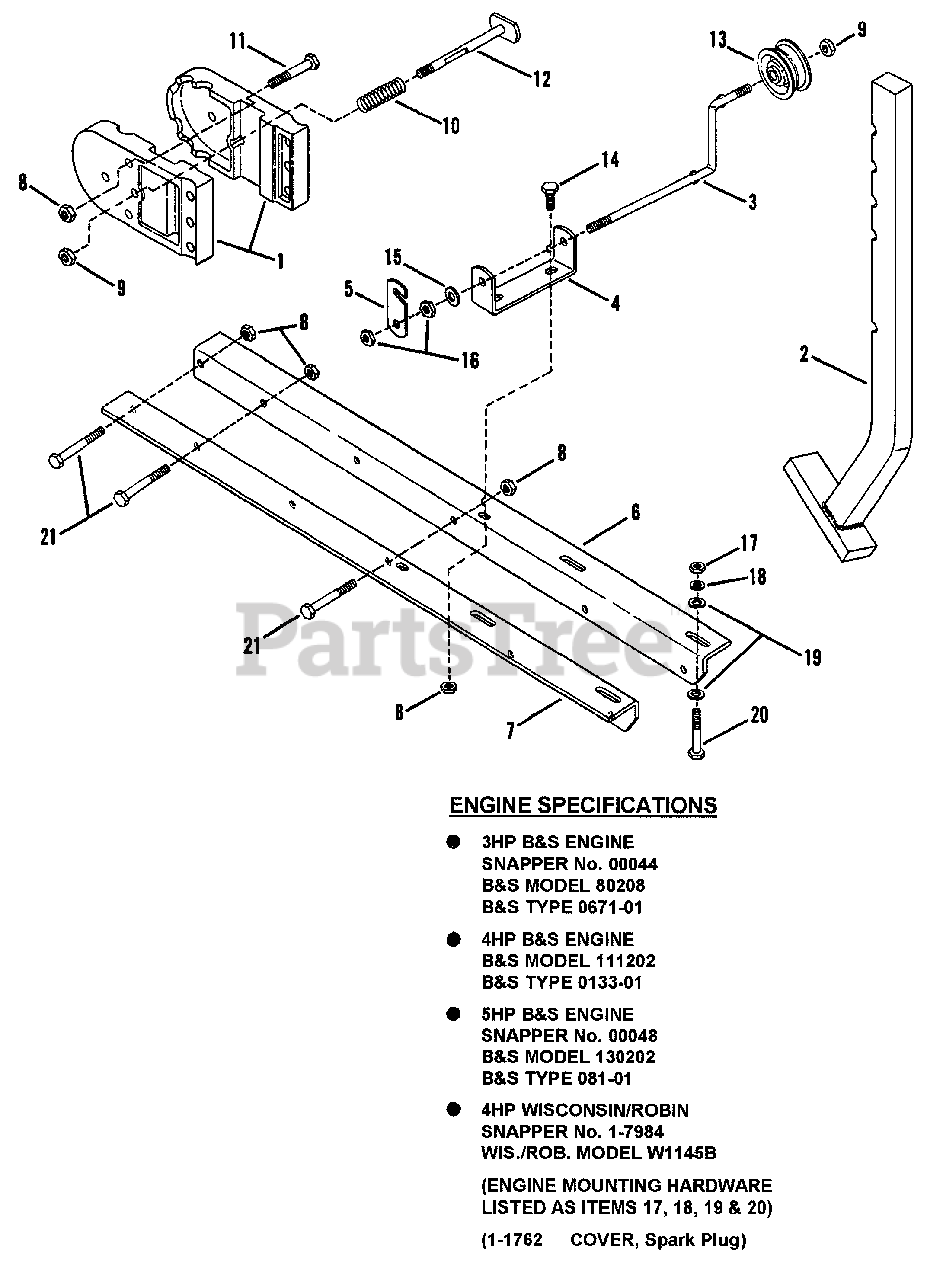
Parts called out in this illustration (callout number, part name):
2	SKID-ARM
3	* ARM, Idler
4	* BRACKET, Idler
5	* LINK, Idler
6	RAIL, Left Hand
7	RAIL, Right Hand
8	NUT, 5/16-24 Hex Center Lock
9	* NUT, 3/8-24 Hex Center Lock
10	SPRING, Pin Release
11	SCREW, 5/16-24 x 2" Hex Head Cap, Gr. 2
12	PIN, Skid Arm Release
13	* PULLEY, Idler
14	SCREW, 5/16-24 x 3/4" Hex Head Cap, Gr. 5
15	* WASHER, 3/8 SAE
16	* NUT, 3/8-24 Hex Gr. 2
17	NUT, 5/16-24 Hex
18	WASHER, 5/16 Split Lock
19	WASHER, 5/16 SAE
20	SCREW, 5/16-24 x 1-3/4" Hex Head Cap, Grade 2
21	SCREW, 5/16-24 x 2-1/2" Hex Head Cap, Grade 5
